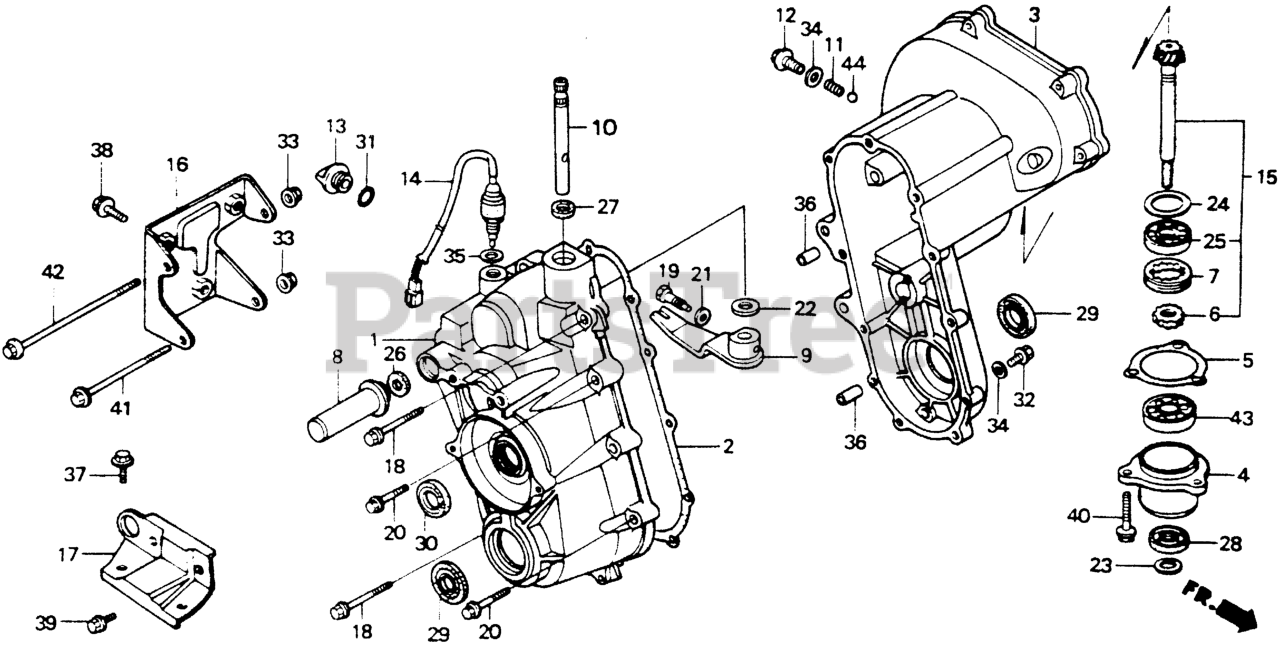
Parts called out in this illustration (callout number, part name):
1	CASE, R. TRANSMISSION
2	GASKET, TRANSMISSION CASE (NOT AVAILABLE)
3	CASE, L. TRANSMISSION
4	HOLDER, INPUT SHAFT
5	GASKET, INPUT SHAFT HOLDER (NOT AVAILABLE)
6	NUT, LOCK (22MM)
7	NUT, LOCK (48MM)
8	COVER, FORK SHAFT
9	ARM, CHANGE SHIFT
10	SHAFT, SHIFT CHANGE
11	SPRING A, BALL SETTING
12	SCREW, BALL SPRING SETTING
14	SWITCH ASSY., NEUTRAL (NOT AVAILABLE)
15	SHAFT, INPUT
16	STAY A, TRANSMISSION
17	STAY B, TRANSMISSION
18	BOLT, FLANGE (6X42)
19	BOLT, SPECIAL (8X24)
20	BOLT, FLANGE (6X32)
21	WASHER, CONICAL SPRING (8MM)
22	WASHER, THRUST (14MM) (NA USE ALT:90451-PC9-000)
23	WASHER (17MM)
24	SHIM A, PINION GEAR (36X43.5X1.25)
24	SHIM B, PINION GEAR (36X43.5X1.30)
24	SHIM C, PINION GEAR (36X43.5X1.35)
24	SHIM D, PINION GEAR (36X43.5X1.40)
24	SHIM E, PINION GEAR (36X43.5X1.45)
24	SHIM F, PINION GEAR (36X43.5X1.50)
24	SHIM G, PINION GEAR (36X43.5X1.55)
24	SHIM H, PINION GEAR (36X43.5X1.60)
24	SHIM I, PINION GEAR (36X43.5X1.65)
24	SHIM J, PINION GEAR (36X43.5X1.70)
24	SHIM K, PINION GEAR (36X43.5X1.75)
25	BEARING, RADIAL BALL (60/22) (TMB)
26	OIL SEAL (12X22X5)
27	OIL SEAL (14X20X3.2)
28	OIL SEAL (20X38X8)
29	OIL SEAL (20X38X10)
30	OIL SEAL (20X31X7)
31	O-RING (16MM)
32	BOLT, DRAIN PLUG (12MM)
33	NUT, FLANGE (8MM)
34	WASHER, DRAIN PLUG (12MM)
35	WASHER, DRAIN PLUG (14MM)
36	PIN A, DOWEL (8X14)
37	BOLT, FLANGE (8X14)
38	BOLT, FLANGE (8X16)
39	BOLT, FLANGE (8X20)
40	BOLT, FLANGE (8X28)
41	BOLT, FLANGE (8X80)
42	BOLT, FLANGE (8X125)
43	BEARING, RADIAL BALL (6204) (TOYO)
44	BALL, STEEL (#10) (5/16)
